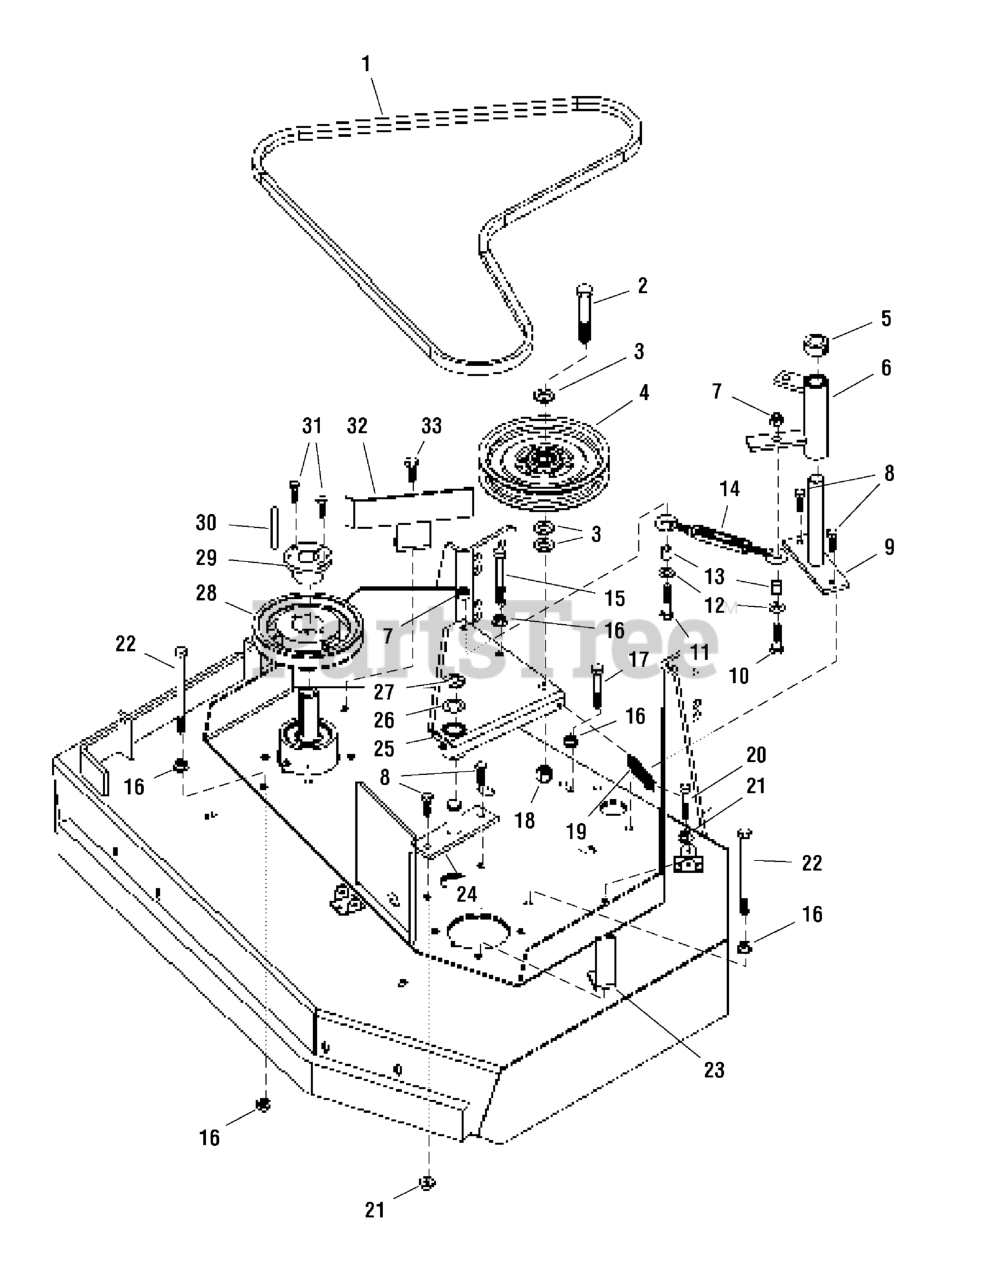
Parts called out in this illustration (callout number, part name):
1	BELT
2	BOLT, 1/2-20 x 3
3	WASHER, 1/2 SAE
4	PULLEY, Backside Idler
4	IDLER PULLEY
5	COLLAR, 3/4" Set
6	BLADE ENGAGE BELL CRANK
6	BUSHING, .75 X 1.00 X 1.00, PLASTIC
7	NUT, 3/8-16 HEX NYLON LOCK
8	BOLT, 5/16-18 X 1 GD5 YZ
8	BOLT, 5/16-18 X 3/4 GD5
9	BLADE ENGAGE PIVOT
10	BOLT, 3/8-16 X 1-1/2" GD5 CZ
11	BOLT, 3/8-16 X 1-3/4" GD5 CZ
12	WASHER, 3/8 SAE
13	SLEEVE
14	TURNBUCKLE ASSY
15	BOLT, 3/8-16 X 3" GD5 CZ
16	NUT, 3/8-16 Hex Serrated Flange
17	BOLT, 3/8-16 X 2-1/4" GD5 CZ
18	NUT, Hex, Nylon Lock, 1/2-20
19	SPRING, Extension
20	BOLT, 5/16-18 x 1-1/2
21	NUT, 5/16-18 HEX SERRATED FLANGE (LARGE)
22	BOLT, 3/8-16 x 5
23	BELT GUIDE
24	IDLER MOUNT
25	CLUTCH PIVOT PLATE
25	BUSHING
26	SHIM
27	C-CLIP
28	PULLEY, Spindle
29	BUSHING, Tapered Hub
30	KEY, 1/4 SQ. X 2-1/2
31	BOLT, 1/4-20 X 1" GD5 CZ
32	BELT GUIDE
33	BOLT, 3/8-16 X 1" GD5 CZ
